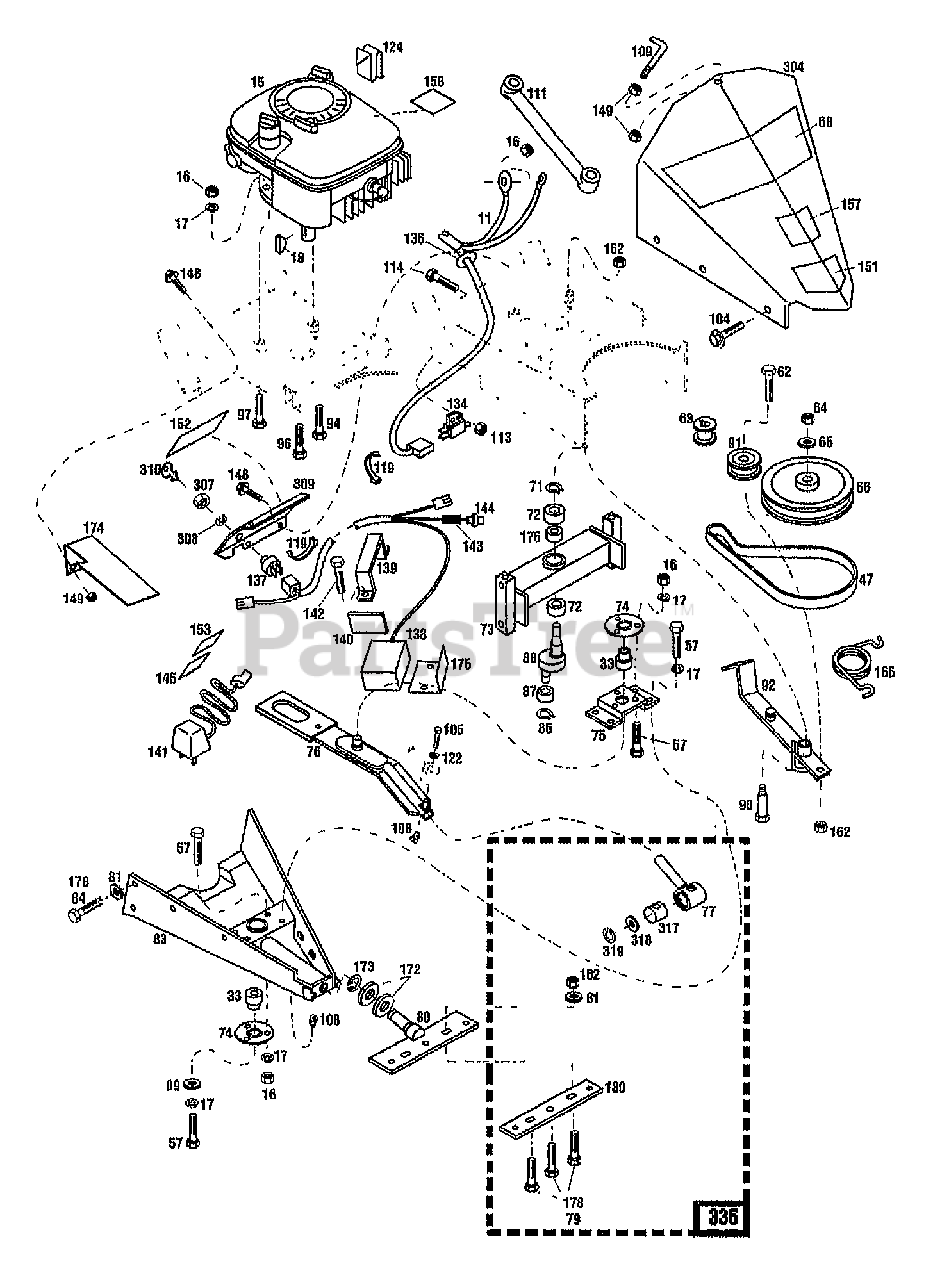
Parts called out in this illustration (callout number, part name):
11	HARNESS-OPERATOR INTERLK (INCL. 134, 313 & 325 PG. 3)
15	ENGINE, BRIGGS & STRATTON, 3.5HP (34061)
15	ENGINE, BRIGGS & STRATTON, 4HP (34062)
15	ENGINE, BRIGGS & STRATTON, 5HP (34063)
15	ENGINE, BRIGGS & STRATTON, 5HP W/ELEC. START (34064)
16	NUT-HEX 5/16-18
17	WASHER-LK .312 INT TOOTH
18	KEY-WOODRUFF .156X.625
33	INSERT-BEARING
57	SCR-HHC 5/16-18X.75 GR 5
62	SCR-HH 3/8-16X1.5 G5
63	PULLEY-ENGINE
64	NUT-HEX 5/8-18
65	WASHER-1.305X.649X.098
66	SHEAVE-ECCENTRIC
68	DECAL-LOGO T/B SICKLEBAR
71	RING-RETAIN EXT .984 ID
72	BEARING-BALL
73	ASSM-ECCENTRIC HSG
74	RETAINER-BEARING
75	SUPT-BEARING UPPER
76	ASSM-ARM ECCENTRIC
77	ASSY-PITMAN (INCL. 317-319)
79	SCR-HHC 3/8-16X1.25 GR8
80	ASSM-BLADE MOUNT BRKT
81	WASHER .905X.390X.084 (HARDENED)
83	ASSM-FRONT HOUSING
84	SCR-HH 3/8-16X.75
86	RING-RETAIN EXT .669 ID
87	BEARING-ECCENTRIC
88	SHAFT-ECCENTRIC
89	WASHER-.312 X 1.378
90	SCR-SHLDR 3/8-16
91	IDLER-SHEAVE 3" X 1"
92	LEVER-BLADE CLUTCH
94	SCR-HH 5/16-18X3.0
96	SCR-HH 5/16-18X4.0 G5
97	SCR 5/16-18X3.00
104	SCR-HFLK 5/16-18X.625 STH
106	SCR-HH 1/4-20X1.25
108	FITTING-GREASE .25-28X90
109	HOOK-UPPER .25
111	DIVERTER-WEED BUNGI
113	NUT W/LKWASHER 10-24
114	SCR-HHS 10-24X.625
119	TIE-CABLE NYLON BLACK
122	WASHER-.75X.312X.065
124	CLIP-CABLE
130	BRKT-DOUBLER
134	SWITCH
135	GROMMET
137	SWITCH-EL IGNITION {34064}
138	BATTERY ES2.9-12 {34064}
139	CLAMP-BATTERY (WB MOWERS) {34064}
140	PAD-BATTERY {34064}
141	CHARGER-BATTERY {34064}
142	SCR-HFLK 1/4-20 X .375 {34064}
143	FUSE-RAMP
144	HARNESS-START {34064}
145	DECAL-ELEC START ENG {34064}
148	SCR 1/4-20X.5 FL SELF TAP
149	NUT-HF/LK 1/4-20
151	DECAL-OPEI CAUTION
152	DECAL-WARN.OPER.INST
153	DECAL-AMERICAN LEGEND-SM
157	DECAL-DNG SHARP CUT BLADE
158	DECAL-WARN.HOT SURFACES
162	NUT-H/LK 3/8-16
166	SPRING-TORSION
172	WASHER-FLAT .059 THK
173	RING-RET EXT .938
174	COVER-INTERLOCK SWITCH
175	REFLECTOR-HEAT {34064}
178	LOCTITE-242 (.5 ML TUBE)
304	HOOD W/DECALS (INCL. 151 & 157)
307	NUT (IGNIT SWITCH) {34064}
308	WASHER-1.0X.64X.029 {34064}
309	PLATE W/DECALS (INCL. 152)
310	KEY-IGNITION {34064}
317	BEARING-PITMAN
318	WASHER-1.115X.637X.06
319	RING-SNAP
